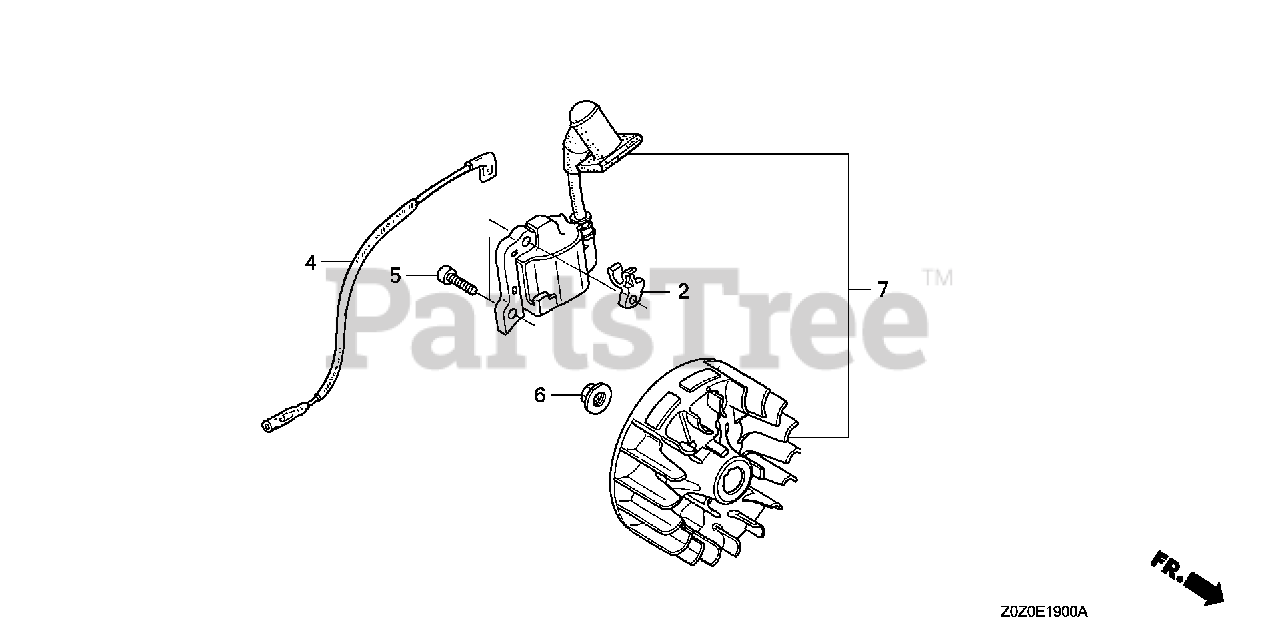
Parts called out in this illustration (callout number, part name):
1	COIL ASSY., IGNITION
2	CLIP, IGNITION WIRE
3	FLYWHEEL
4	WIRE, STOP SWITCH
5	BOLT, SOCKET (4X14)
6	NUT, FLANGE (8MM)
7	IGNITION COIL & FLYWHEEL KIT (TEC)
